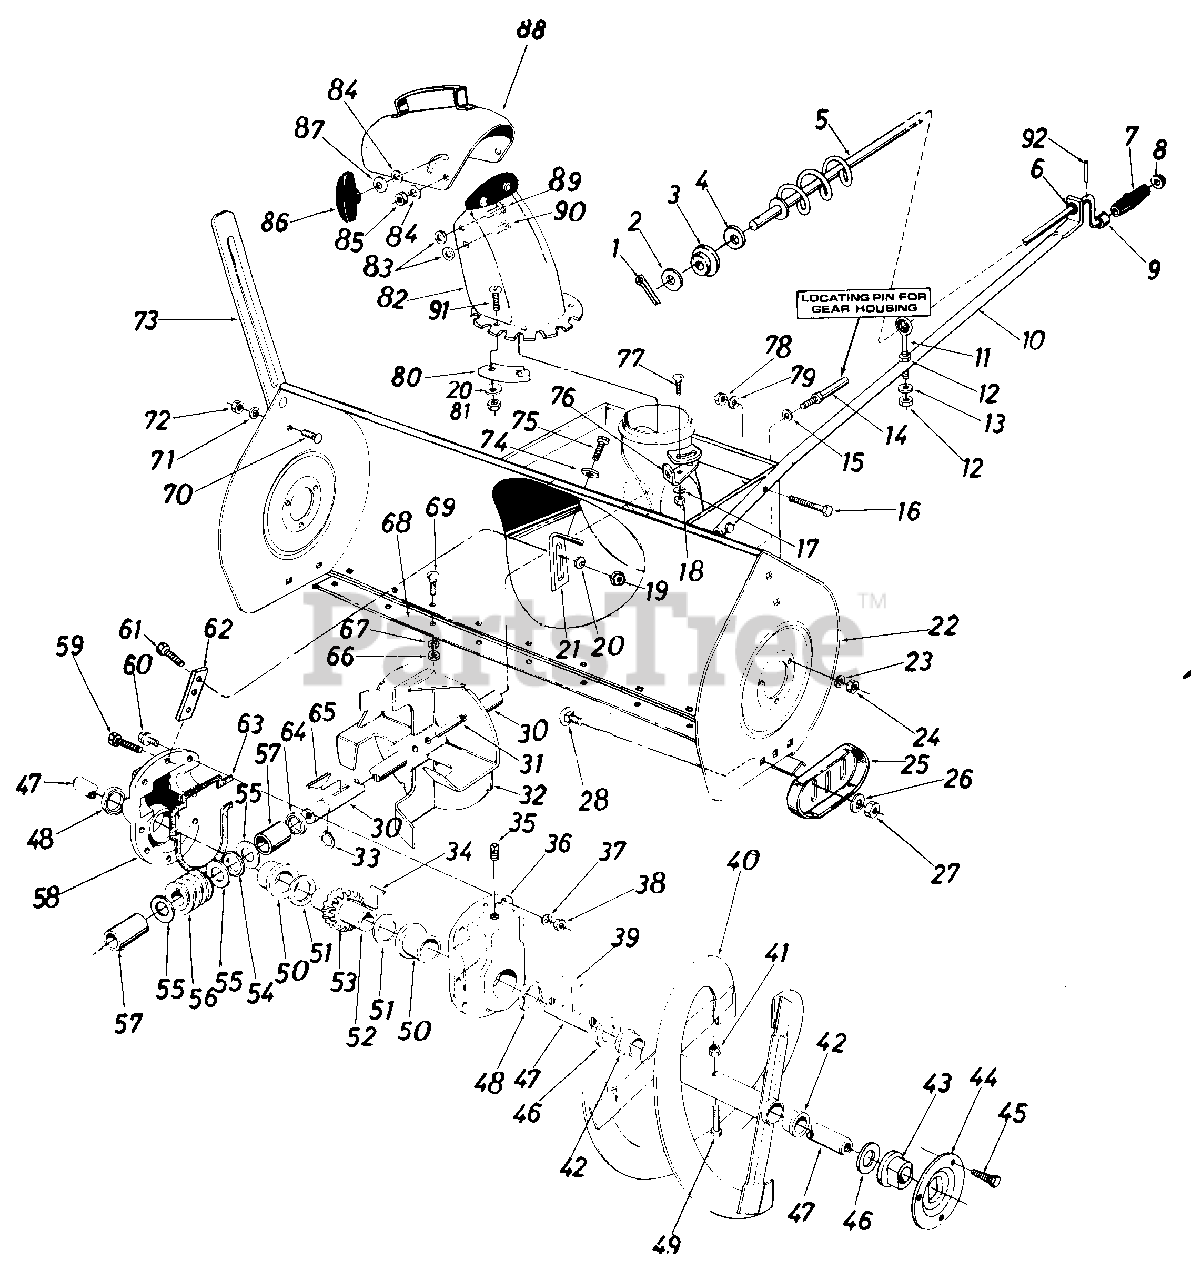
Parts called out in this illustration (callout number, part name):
2	Fl.-Wash. .39" I.D. x .62" O.D.
3	Plastic Bushing
4	Fl.-Wash. .385" I.D. x .62" O.D.
5	Chute Crank Ass'y.
6	Plastic Bushing
7	Knob (Black)
8	Push Nut 3/8" Rod
9	Spacer .385 I.D. x .50" I.D.
10	Chute Crank Support Tubing
12	Hex Nut 5/16-18 Thd.*
13	Bell.-Wash. .345" I.D. x .88" O.D.
14	Stud 3/8-16 x 2.75" Lg.
15	Bell.-Wash. .400" I.D. x.88"-O.D.
16	Hex Bolt 3/8-24 x 1.25" Lg.*
17	Bell.-Wash. .345" I.D. x .88" O.D.
18	Hex Nut 5/16-18 Thd.*
19	Hex Nut 1/4-28 Thd.
20	Bell.-Wash. .265" I.D. x .75" O.D.
22	45" Snow Blower Housing Ass'y
23	L.-Wash. 5/16" I.D. *
24	Hex Nut 5/16-18 Thd.*
25	Slide Shoe
26	Bell.-Wash. .400" I.D. x.88" O.D.
27	Hex Jam Nut 3/8-16 Thd.
28	Carriage Bolt 3/8-16x .62" Lg.*
30	Blower Axle .875" Dia. x 14.75" Lg.
31	Spring Pin Spir. 5/16" Dia. x 1.75" Lg.
34	#91 Woodr-Key 1/4 x 3/4" Dia. (HDN)
36	Comp. Gear Hsg. Half-L.H.
37	Spr.-Wash. .32" I.D. x .62" O.D
38	Hex Ins. L.-Nut 5/16-18 Thd.
39	#91 Woodr-Key 1/4 x 3/4" Dia. (HDN)
41	Hex Ins. L.-Nut 5/16-18 Thd.
42	Plastic Bushing
43	Flange Brg. w/flats 1" I.D.
44	Bearing Housing
45	Hex Sems Bolt 5/16-18 x .75" Lq. *
46	Fl.-Wash. 1.00" I.D. x 1.75" O.D.
48	Flange Bearing 1.503" I.D.
49	Shear Bolt 5/16-18 x 1.75" Lg.
50	Oil Seal 1.50" I.D.
51	Fl.-Wash.1.50" I.D. x2.00" O.D.
52	Worm Gear Shaft
53	Double Threaded Worm Gear-L. H .
54	Thrust Brg.-.88" I.D. x 1.44" O.D.
55	Fl.-Wash..88" I.D. x 1.4" O.D.
56	Double Threaded Worm-L.H.
57	Sleeve
58	Complete Gear Hsg. Half-R.H.
59	Hex Bolt5/16-18x1.25" Lg.*
60	Hex Bolt 5/16-18 x 1.0" Lg. (Grade 5)
61	Hex Bolt 1/4-28 x .75" Lg.
62	Gear Housing Support Plate
63	Rubber Gasket
64	Oil Seal-.875" I.D.
65	#9 Hi-Pro Key 3/16 x 3/4" Dia. (HT.)
66	Hex Nut 5/16-18 Thd.*
67	L.-Wash. 5/16" I.D.*
69	Carriage Bolt 5/16-18 x 1.00" Lg. *
70	Carriage Bolt 5/16-18 x .62"-Lg.*
71	L.-Wash.5/16" I.D.*
72	Hex Nut 5/16-18 Thd.*
73	Guide Blade
74	Bell.-Wash. .345" I.D. x .88" O.D.
75	Hex Wash. Hd. AB Tap Scr 5/16 x .75" Lg.
77	CarriageBolt5/16-18 x.75" Lg.*
78	Hex Ins. L.-Nut3/8-24Thd.
79	L.-Wash. 3/8" I.D.*
80	Chute Flange Keeper
81	Hex L-Nut 1/4-20 Thd.
82	Chute Ass'y. w/Chute G uard
83	Fl.-Wash. .285" I.D. x 1.25" O.D.
84	Bell.-Wash. .345" I.D. x .88" O.D.
85	Hex Cent. L.-Nut 5/16-18 Thd.
86	Knob Handle
87	Bell.-Wash. .345" I.D. x .88" O.D.
88	Top Chute Ass'y.
89	Carriage Bolt 5/16-18 x 1.00" Lg.*
90	Carriage Bolt 5/16-18 x .62" Lg.*
91	Truss Mach. Scr. 1/4-20 x .75"
92	Roll Pin .12 Dia. x .63"
